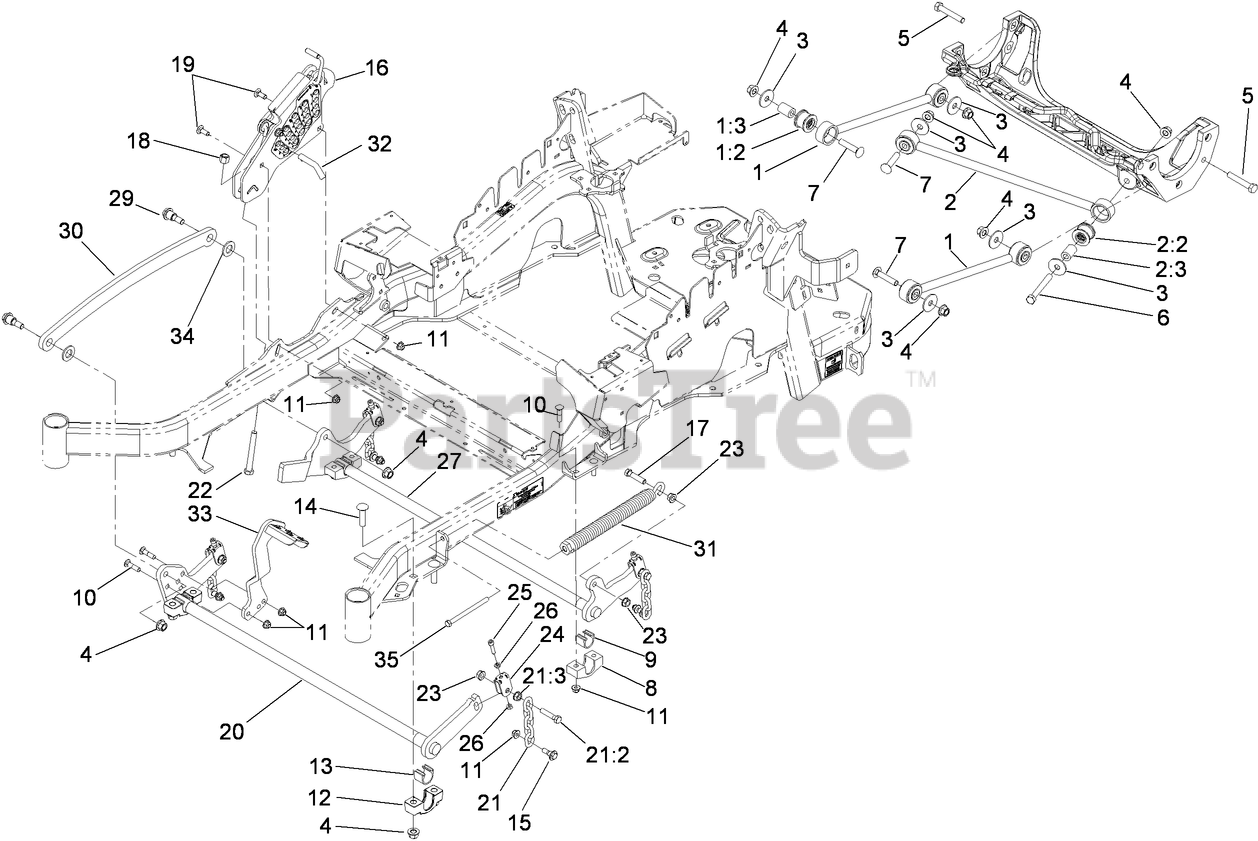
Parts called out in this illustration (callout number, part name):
1	DECK STRUT ASM
1:2	BUSHING-SUSPENSION, RUBBER
1:3	SPACER
2	PANHARD ROD ASM
2:2	BUSHING-SUSPENSION, RUBBER
2:3	SPACER
3	WASHER-THRUST
4	NUT-LOCK
5	SCREW-HH
6	SCREW-HH
7	SCREW-CARR
8	SUPPORT-BEARING, CROSS SHAFT
9	BEARING-CROSS SHAFT, REAR
10	SCREW-CARR
11	NUT-HF, NI
12	SUPPORT-CROSS SHAFT, BEARING
13	BEARING-CROSS SHAFT, FRONT
14	SCREW-CARR, SHORT NECK
15	SCREW-SHOULDER, HHF
16	HOC ASM
17	SCREW-HH
18	NUT-LOCK, NI
19	BOLT-CARR
20	LIFT-DECK, FRONT
21	DECK LIFT CHAIN ASM
21:2	SCREW-HH
21:3	NUT-HF
22	BOLT-TAP
23	NUT-HF
24	YOKE-ADJUST, DECK
25	SCREW-HSH
26	NUT-JAM
27	LIFT-DECK, REAR
29	SCREW-SHOULDER, HHF
30	LINK-LIFT, DECK
31	SPRING-EXTENSION
32	PIN-HOC
33	LEVER-FOOT
34	WASHER-FLAT
35	BOLT-TAP, HH
